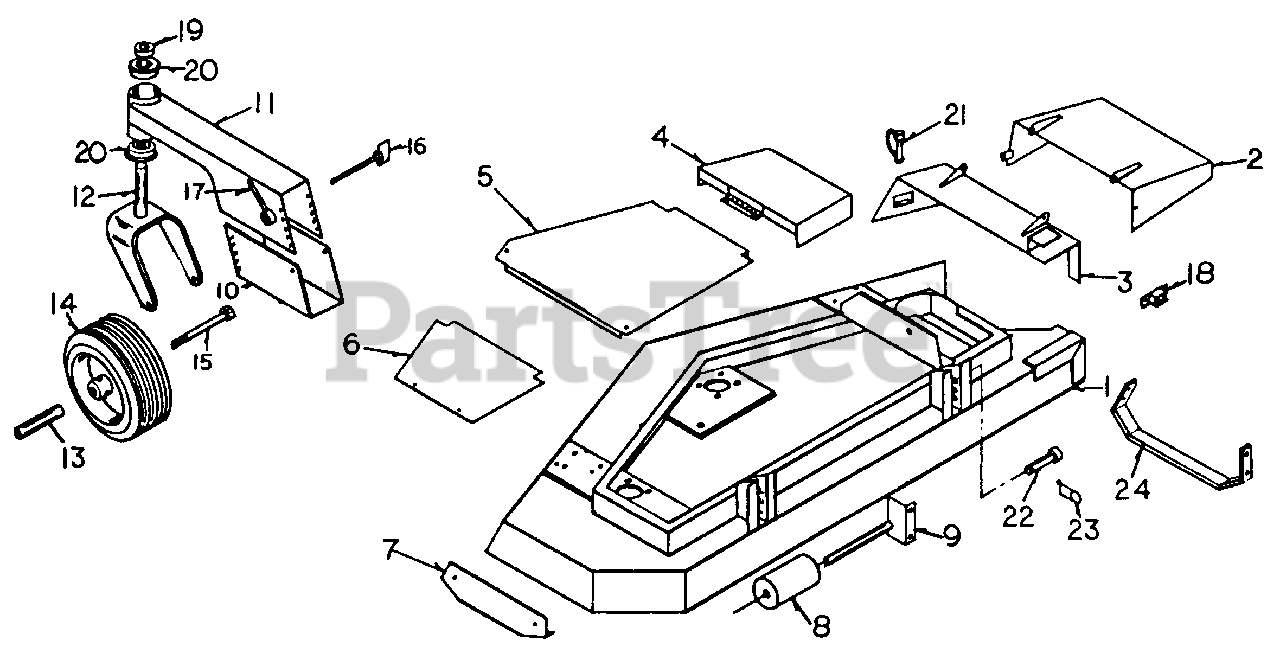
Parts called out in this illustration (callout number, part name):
1	62" Deck
3	Foot Guard Mount
8	Anti-scalp Roller
9	Shaft & Bracket
10	Gauge Wheel Mount Bracket
11	Gauge Wheel Mount
13	Axle
14	Gauge Wheel Assembly
18	10 Amp Circuit Breaker
19	Set Collar, 1"
23	Hair Pin Cotter
24	Shoe, RH
